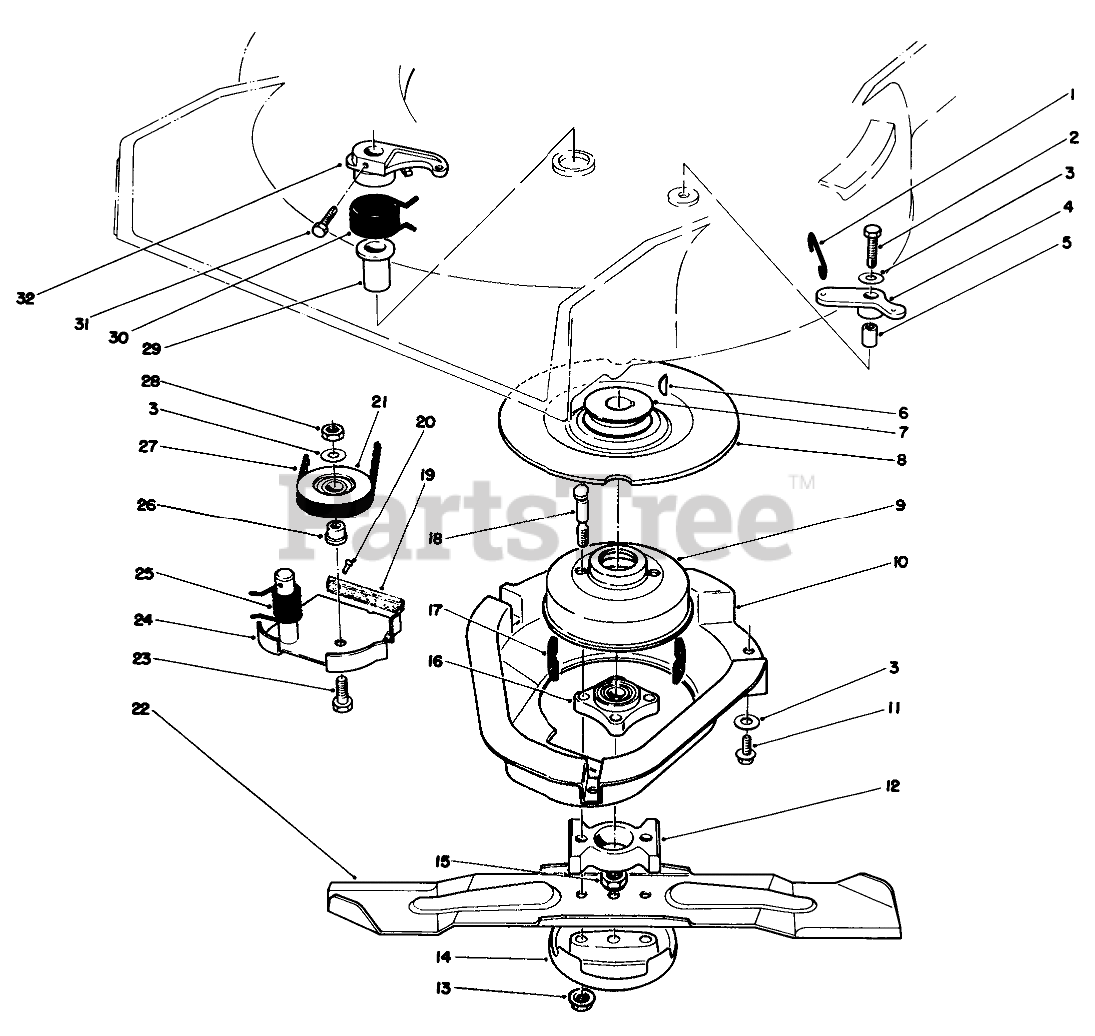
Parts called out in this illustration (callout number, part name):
1	LINK-CONTROL
2	SCREW-HH
3	WASHER-PLAIN
4	BELLCRANK
5	SLEEVE-BELLCRANK
6	KEY-WOODRUFF
7	PULLEY-DRIVER
7	PULLEY
8	Flywheel
9	Drum-Brake
10	SHIELD BBC
11	SCREW-HWHTF
12	Spacer Blade
13	NUT-LOCK
14	Anti Scalp Cup
15	NUT-LOCK, NI
16	HUB ASM
17	DAMPENER-VIBRATION
18	BOLT-BLADE
19	Paid
20	.185 DIA X .375 RT +
21	PULLEY-IDLER
22	BLADE-21in
23	SCREW-HH
24	Brake Plate (Incl. Ref. #19 & 20)
25	SPRING-TORSION
26	HUB-PULLEY, IDLER
27	V-BELT
28	NUT-LOCK, NI
29	BUSHING PM
30	SPRING-TORSION
31	SCREW-HH
32	LEVER
